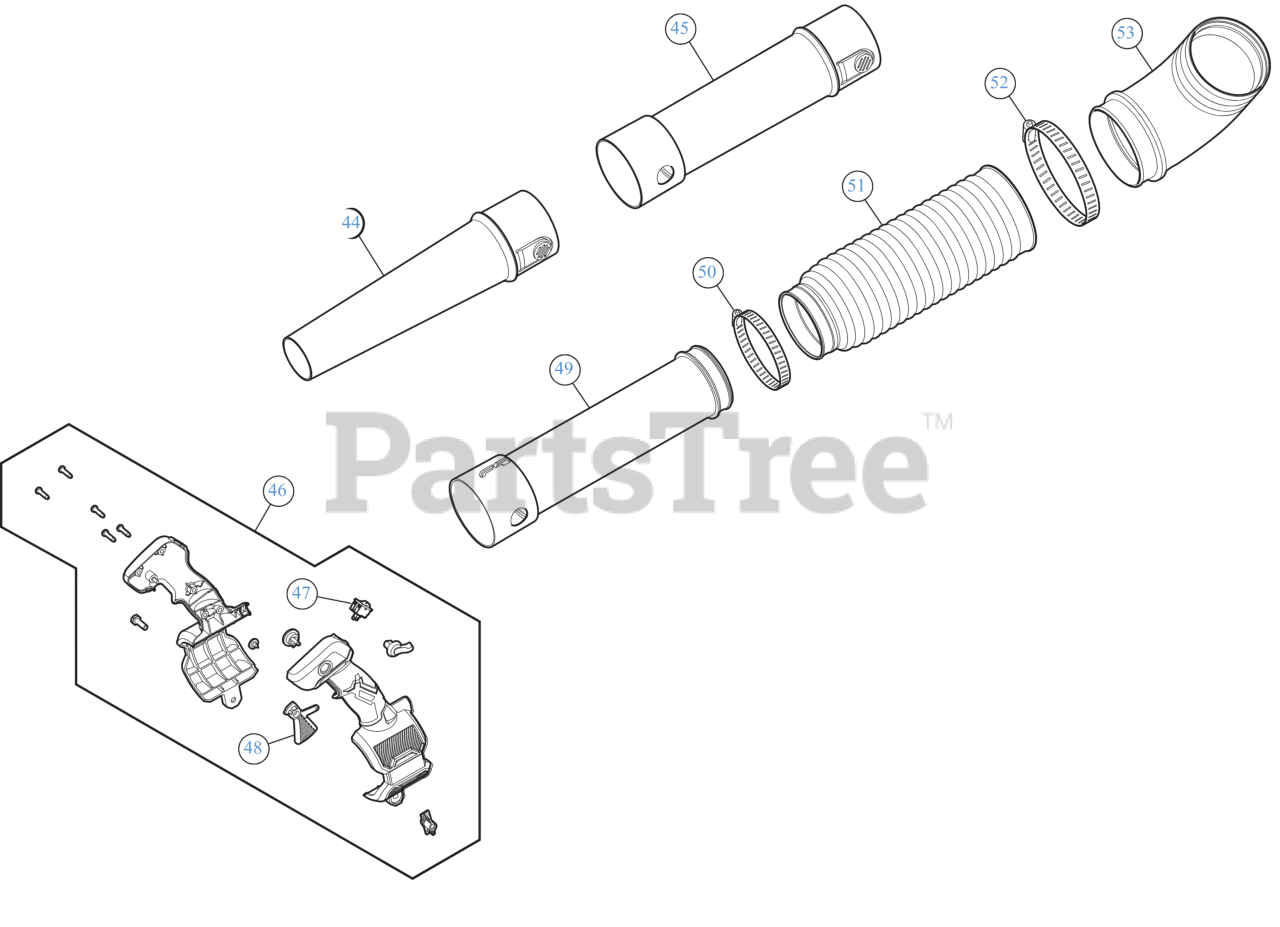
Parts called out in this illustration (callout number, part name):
44	LOWER TUBE
45	UPPER TUBE
46	THROTTLE GRIP
47	MOMENTARY SWITCH ON/OFF
48	THROTTLE TRIGGER
49	TUBE GRIP W/SWIVEL
50	HOSE CLAMP
51	FLEX TUBE
53	ELBOW TUBE
